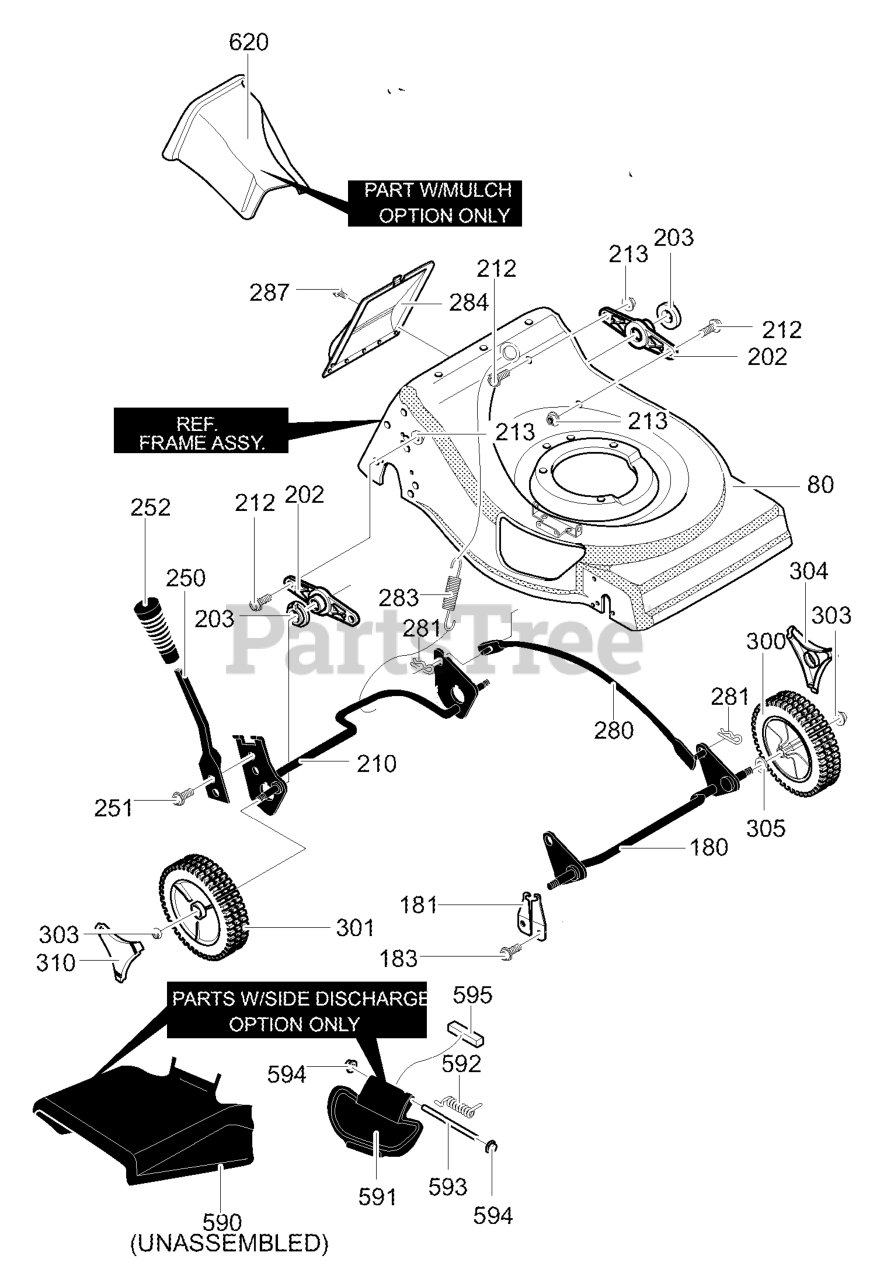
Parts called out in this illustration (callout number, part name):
80	ASSY, FRAME
180	CROSSBAR, FRONT
181	BUSHING
202	SUPPORT, AXLE
203	BEARING, LIFTER
210	ASSY, CROSSBAR
212	SCREW, 5/16-18 x 0.75
250	LEVER, SPRING
252	KNOB, HEIGHT ADJ
280	ASSY., LINK LIFTER
281	HAIR PIN
283	SPRING, EXTENSION
284	COVER, REAR
287	SCREW, 1.4-20X.63
300	TIRE & RIM
301	TIRE & RIM
304	HUB CAP
305	SPRING WASHER
310	HUB CAP
590	DEFLECTOR, CHUTE
591	COVER, MULCH
592	SPRING, TORSION
593	ROD, PIVOT
594	CAP, PUSH ON
595	SEAL, FOAM
620	PLUG, MULCHER
